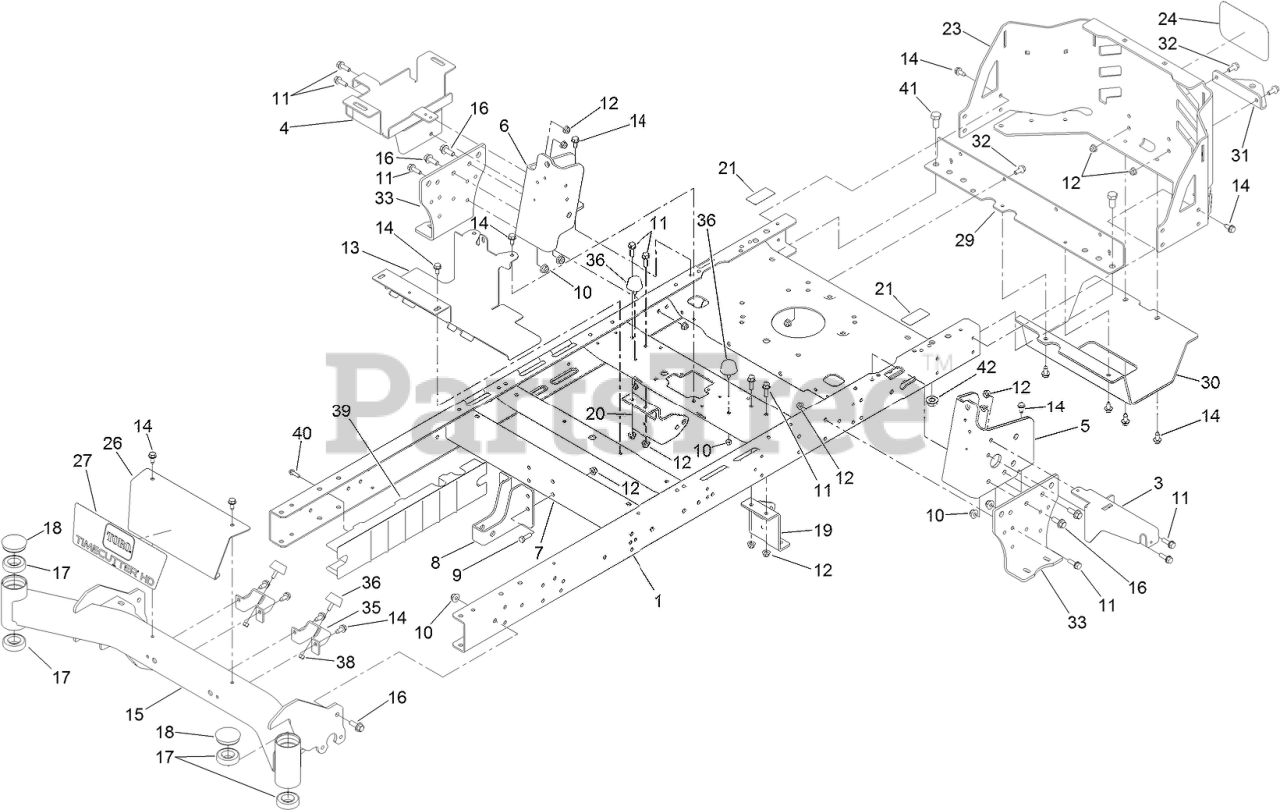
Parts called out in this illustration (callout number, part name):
1	FRAME ASM
3	BRACKET-POD SUPPORT, LH
4	TRAY-BATTERY
5	BRACKET-MOUNTING, LH
6	BRACKET-MOUNTING, RH
7	BRACE-CROSS, LOWER
8	BRACKET-MOUNT DAMPER, LOWER
9	SCREW-HH
10	NUT-HF, NI
11	SCREW-HHF
12	NUT-HF, NI
13	BRACKET-MOUNT
14	SCREW-HWHTF
15	AXLE-FRONT
16	SCREW-HHF
17	BEARING-BALL
18	CAP-GREASE
19	MOUNT-HYDRO, FRONT (LH)
20	MOUNT-HYDRO, FRONT (RH)
21	DECAL-BYPASS
23	GUARD-ENGINE
24	DECAL
26	PLATE-FRONT
27	DECAL-TIMECUTTER HD
29	CROSSMEMBER-REAR
30	GUARD-MUFFLER
31	BRACKET-HITCH
32	SCREW-HHF
33	MOUNT-HYDRO
35	BRACKET-STOP, BUMP
36	BUMPER
38	NUT-LOCK, NI
39	GUARD-RAIL
40	SCREW-HWH
41	SCREW-HH
42	NUT-LOCK
